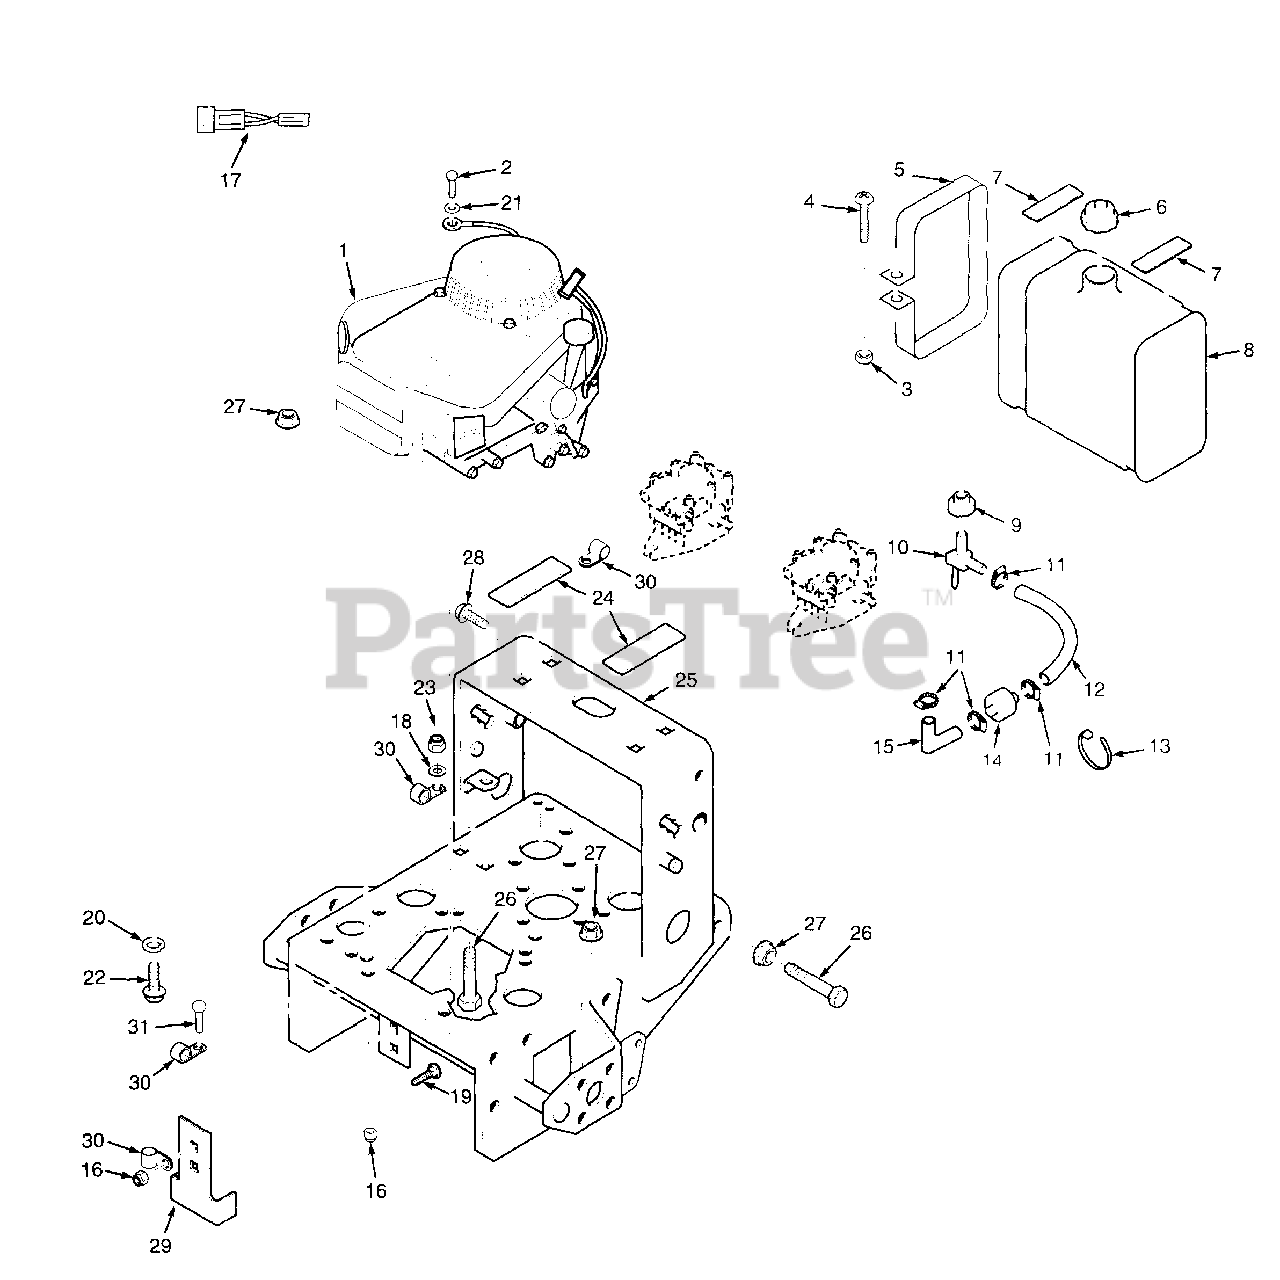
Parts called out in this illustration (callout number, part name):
1	Engine, 17KA Kawasaki
2	Bolt, Hex Head M8-1.25 x 10mm
3	Hex Nut, 1/4-20
4	Screw, 1/4-20 x 2" Rnd. Hd Phillips
5	Strap, Fuel Tank
6	Cap, Fuel Tank
7	Pad, Rubber-Fuel Tank Upper
8	Fuel Tank Assembly
9	Bushing
10	Valve, Fuel Shut-Off
11	Clamp, Fuel Hose
12	Fuel Hose, 1/4 I.D. x 20"
13	Cable Tie
14	Fuel Filter
15	Fuel Hose, 7/32 I.D. x 3.5"
16	Nut, Hex Elastic Stop 5/16-18
17	Wire Harness Adapter, 17KA
18	Flat Washer, 14"
19	Bolt, Carriage 5/16-18 x 1"
20	Lock Washer, 5/16"
21	Lock Washer, 5/16" Int. Tooth
22	Bolt, Hex Head M8-1.25 x 30mm
23	Nut, Hex Elastic Stop 1/4-20
24	Pad, Rubber-Fuel Tank Lower
25	Engine Deck, 16" Wide W/Decals
26	Bolt, Hex Head 1/4-20x 1.25"
27	Nut, Hex Serrated Flange 1/4-20
28	Capscrew, Hex Serrated Flange 5/16-18 x 1.25"
30	Clutch Bracket
31	Bolt, Hex Head 5/16-18 x .75"
